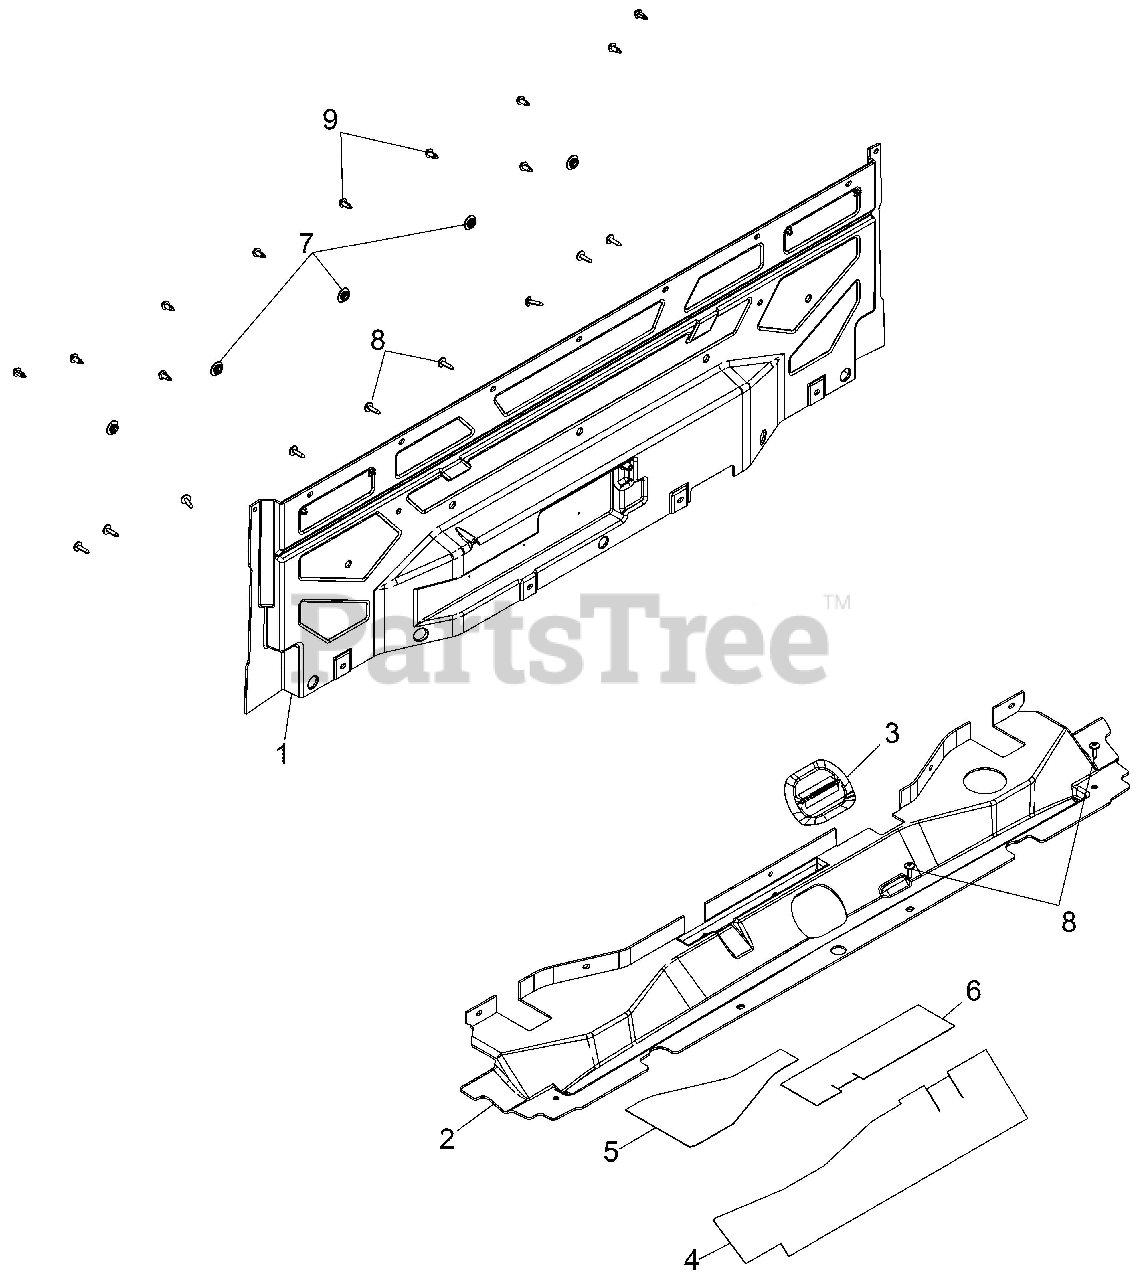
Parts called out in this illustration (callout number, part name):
1	PANEL-CLOSEOFF,REAR,BLK
2	PANEL-CLOSEOFF,LOWER,BLK
3	PLUG, CLOSEOFF, DUCT
4	FOIL-CLOSEOFF,FRONT
5	FOIL-CLOSEOFF
6	FOIL-CLOSEOFF,FRONT
7	PLUG-COMPARTMENT
8	SCR-TXTH-M6X1.0X25 RIE
9	RIVET-TUFLOK,.315-.325X.787 (5
